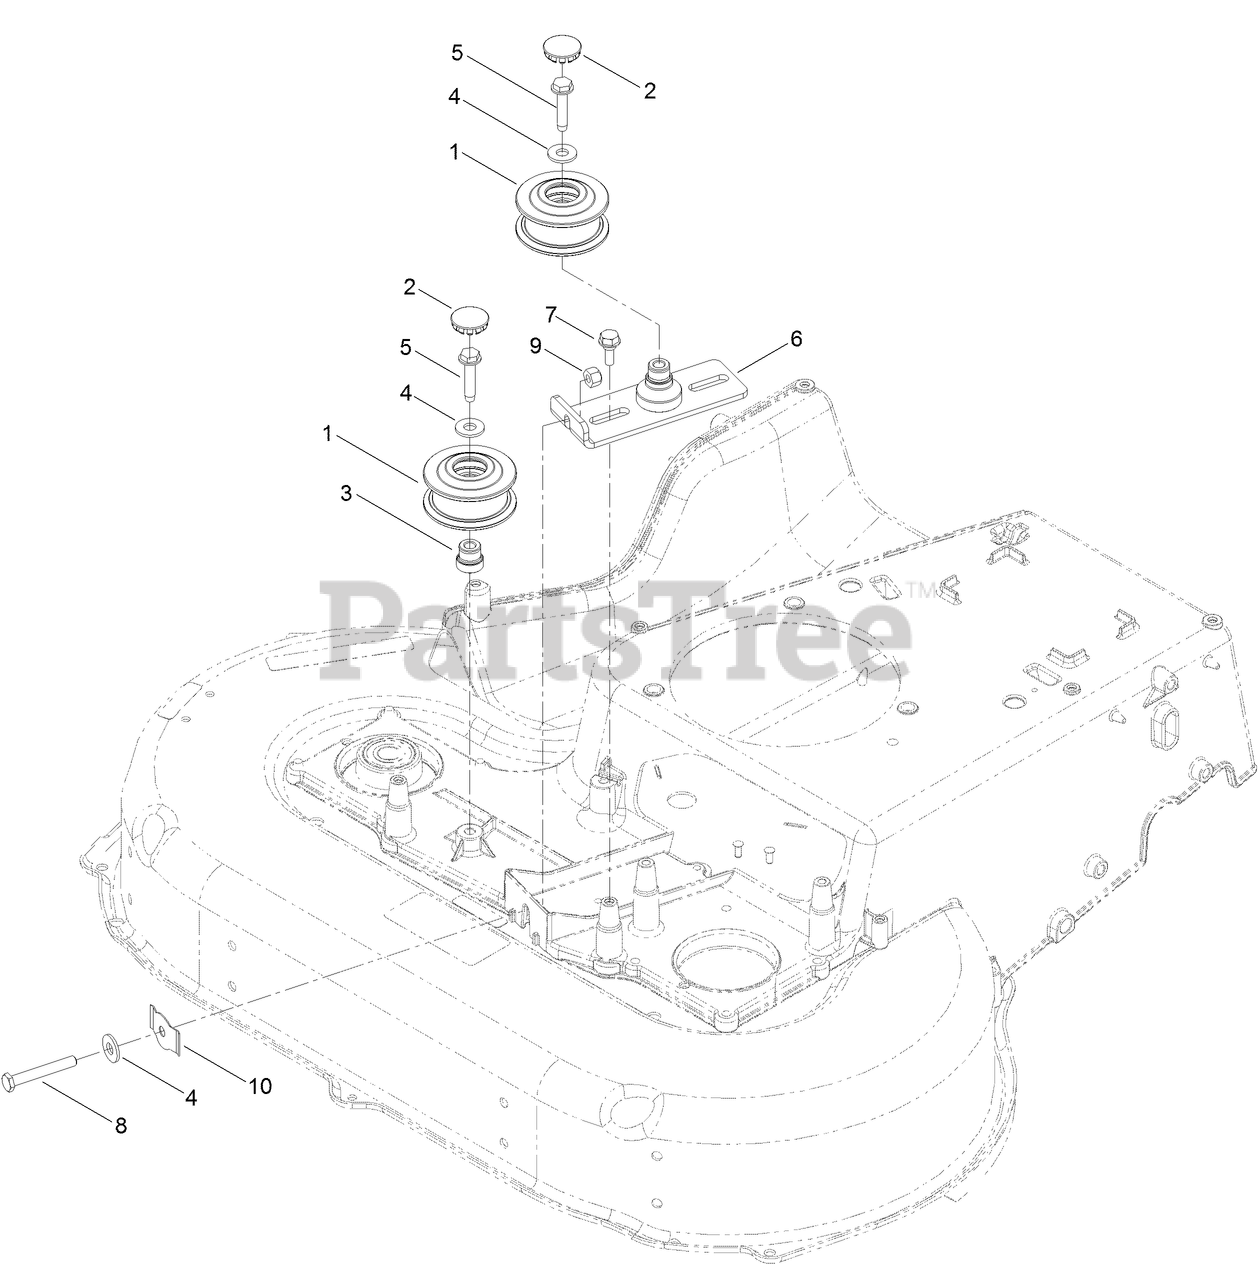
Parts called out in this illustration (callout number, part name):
1	PULLEY-IDLER, FLAT
2	PLUG-BUTTON
3	ADAPTER-BORE
4	WASHER-FLAT
5	SCREW-HWH
6	BRACKET-IDLER
7	SCREW-SHOULDER, HHF
8	BOLT-TAP, HH
9	NUT-LOCK, NI
10	SPRING-FLAT
